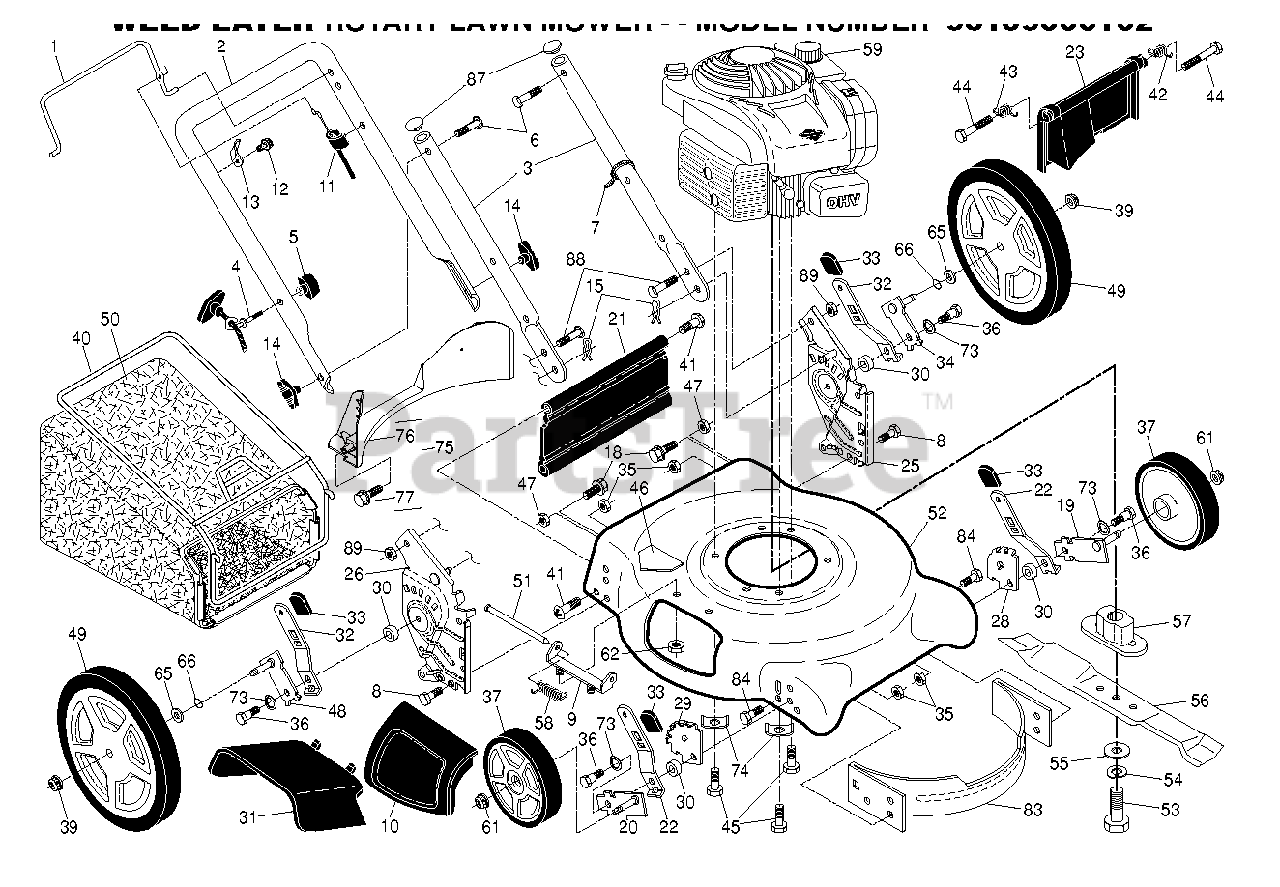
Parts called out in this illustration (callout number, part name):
1	BAIL.CONT.D.STRAIGHT.PUSH.BLK
2	HANDLE.UPPER.ECONOMY.BLACK
3	HANDLE.LOWER.DOME.BT.BLACK
4	Rope Guide, Blk Zinc Chrom
5	T-KNOB.NEW ROPE GUIDE
6	BOLT, HANDLE 5/16-18X1.75
7	TIE GUIDE
8	BOLT
9	BRACKET.ASM.HOUSING.EZ.MUL
10	MULCH DOOR
11	CABLE.MZR.RATO.22"LOW.
13	BRACKET.UPSTOP.RT
15	HAIRPIN COTTER
18	SCREW 1/4X20
19	AXLE ARM ASSY FRONT LH
20	AXLE ARM ASSY FRONT RH
21	KIT.SKIRT.21 DOMED.W/LIP
22	SELECTOR SPRING, FRONT
23	REAR DOOR ASSY
25	BRACKET.ASM.HANDLE.HW.21.LT.BL
26	BRACKET.ASM.HANDLE.HW.21.RT.BL
28	BRACKET.ADJ.5.RTAB.LG.HOLE.ABS
29	BRACKET.ADJ.5.LTAB.LG.HOLE.ABS
30	SPACER.HEIGHT.ADJUSTER
31	CLIP ON DISCHARGE GUARD
32	SPRING.SEL.22.ECON.HI-WHL.RATO
34	Axle Arm Assembly, .Lr.5/9.Pos.Bzp
35	NUT.FLANGE.HEX.5/16X18.BLACK
36	SHOULDER BOLT 5/16-18
37	WHEEL.7X1.75.5SPK.BRK.BLACK
39	NUT.HEX.FLANGE.3/8-16.LOCKNUT
40	FRAME.BAG.21.REAR.DOMED.PUSH
41	SCREW.1/4-20X21/4.HEX.
42	SPRING.LH.22.REAR.DOOR.EZ.EMPT
43	SPRING.RH.22.REAR.DOOR.EZ.
45	BOLT 3/8-16X1-1/8
46	No Step Decal
47	NUT.LOCK.5/16-18
48	Axle Arm Assembly, RR 5/9 Pos BZP
49	WHEEL.12X1.75.5SPK.BRK.BLACK
50	GBAG.24710612.BLK.WEAT
51	ROD.HINGE.COMBI-C
53	SCREW, HEX HD 3/8-24 X 1-3/8
55	WASHER,HARDEN
56	BLADE.21.PUSH/RWGD/FWGD
57	ADAPTOR.BLADE.7/8
58	TORSION SPRING
61	NUT.HEX.FLANGE.3/8-16.LOCKNUT
62	LOCKNUT.NYLOC.1/4-20
65	WASHER PM
66	O-RING..070X.487.NEOPRENE
73	WASHER.CURVED.CYLINDRICAL
74	WASHER.ENGINE.BZP
75	KIT.BAFFLE.REAR.PLASTIC.21.RD
76	BAFFLE.REAR.PLASTIC.21.RD.ECON
77	SCREW.HX.13X.750
83	BAFFLE.FRONT.21.DOME.US
84	BOLT.5/16HEX.WHS.HD
87	PLUG.PLASTIC.7/8".14-20.GAUGE
89	LOCKNUT-FLANGE 5/16-18
